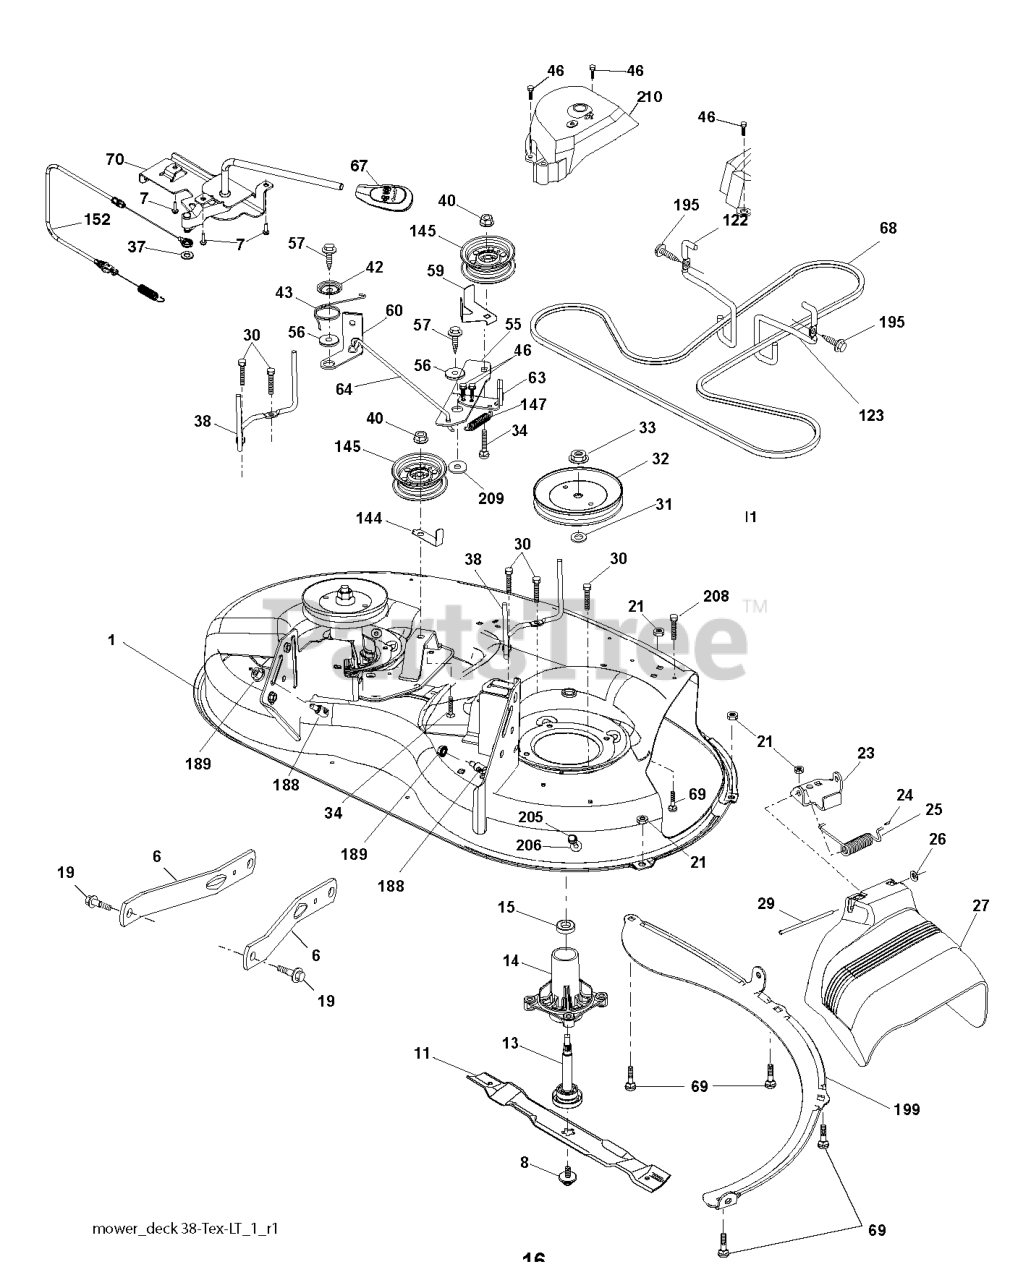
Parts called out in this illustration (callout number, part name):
1	HOUSING
6	ARM.SUSPENSION.MOWER.R
7	SCREW
8	BOLT.WASHER.ASM.7/16-2
11	BLADE 38" PREMIUM
13	SHAFT.ASM.MDRL.N/GREASE.38
14	RP.HOUSING.MANDREL.4PT.
19	BOLT.SHOULDER
21	LOCKNUT
23	BRKT.DEFLECTOR.38"2005+
24	CAP-SLEEVE LT
25	SPRING.TORSION.DEFLECT
26	NUT PUSH M
27	SHIELD ASM.DFLCTR MWR.38-7"BLK
29	ROD.HINGE
30	SCREW, WASHER HEAD
31	WASHER.SPACER.MANDREL
32	PULLEY.MANDREL.5.0.PD.38"
33	NUT.FLANGE.LOCK.TOP
34	BOLT.3/8-16X1.50
37	WASHER
38	KEEPER BELT LH MANDREL
40	NUT LOCK FLG 3/8-16 UNC
42	SPRING.TORSION.BRAKE
43	SRPING.TORSION.RETAINE
46	SCREW.1/4-20X5/8
56	SPACER.RETAINER
57	SCREW 3/8-16X1
59	GUARD, BELT
60	ARM BRAKE MOWER RH 38"
63	RP ARM.BRAKE.MOWER.38"LH.TEX
64	LINK BRAKE
67	HANDLE.CLUTCH.CABLE.LT
69	BOLT
70	CLUTCH.ASM.MANUAL.LT.PRED
122	KEEPER BELT ENGINE LH
123	KEEPER BELT RH
144	KEEPER BELT
145	PULLEY.IDLER.48"PRIMARY
147	SPRING RETURN
152	CLUTCH CABLE
188	STUD.FASTNER.W/ANTI-ROTATE
189	NUT LOCK HEX FLANGE 5/16-18
195	SCREW, 3/8-16X3/4
199	BAFFLE.VORTEX.FRONT.38"
205	SCREW
208	SCREW 3/8-16X1/2
209	WASHER 12/32X2X10GA
